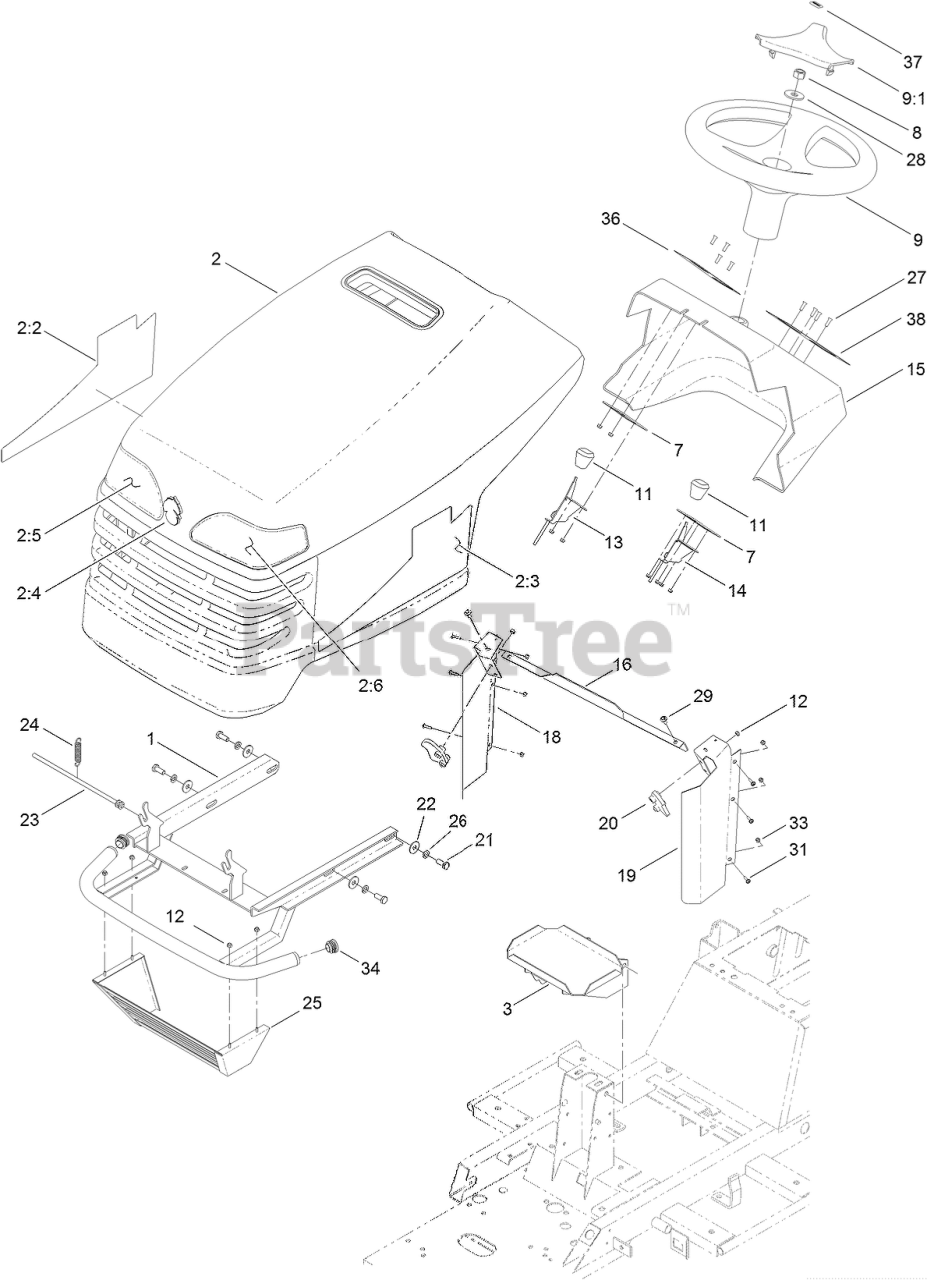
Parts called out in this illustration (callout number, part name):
1	SUPPORT-BUMPER
2	HOOD ASM
2:2	DECAL-HOOD, RH
2:3	DECAL-HOOD, LH
2:4	EMBLEM
2:5	LENS-HEADLAMP, RH
2:6	LENS-HEADLAMP, LH
3	TRAY-BATTERY
8	NUT-LOCK
9	WHEEL-STEERING
9:1	COVER-WHEEL, STEERING
12	NUT-LOCK
13	CONTROL-THROTTLE (TWIN)
14	CONTROL-CHOKE (TWIN)
15	PANEL-DASH
18	PANEL-RIGHT
19	PANEL-LEFT
20	LATCH-HOOD
21	SCREW-HH
22	WASHER-PLAIN
24	SPRING-HOOD
25	GUARD-MUFFLER
26	WASHER-LOCK
28	Washer
33	NUT-HEX
34	PLUG-END, TUBE
36	DECAL
37	DECAL
38	DECAL-CHOKE/PTO
